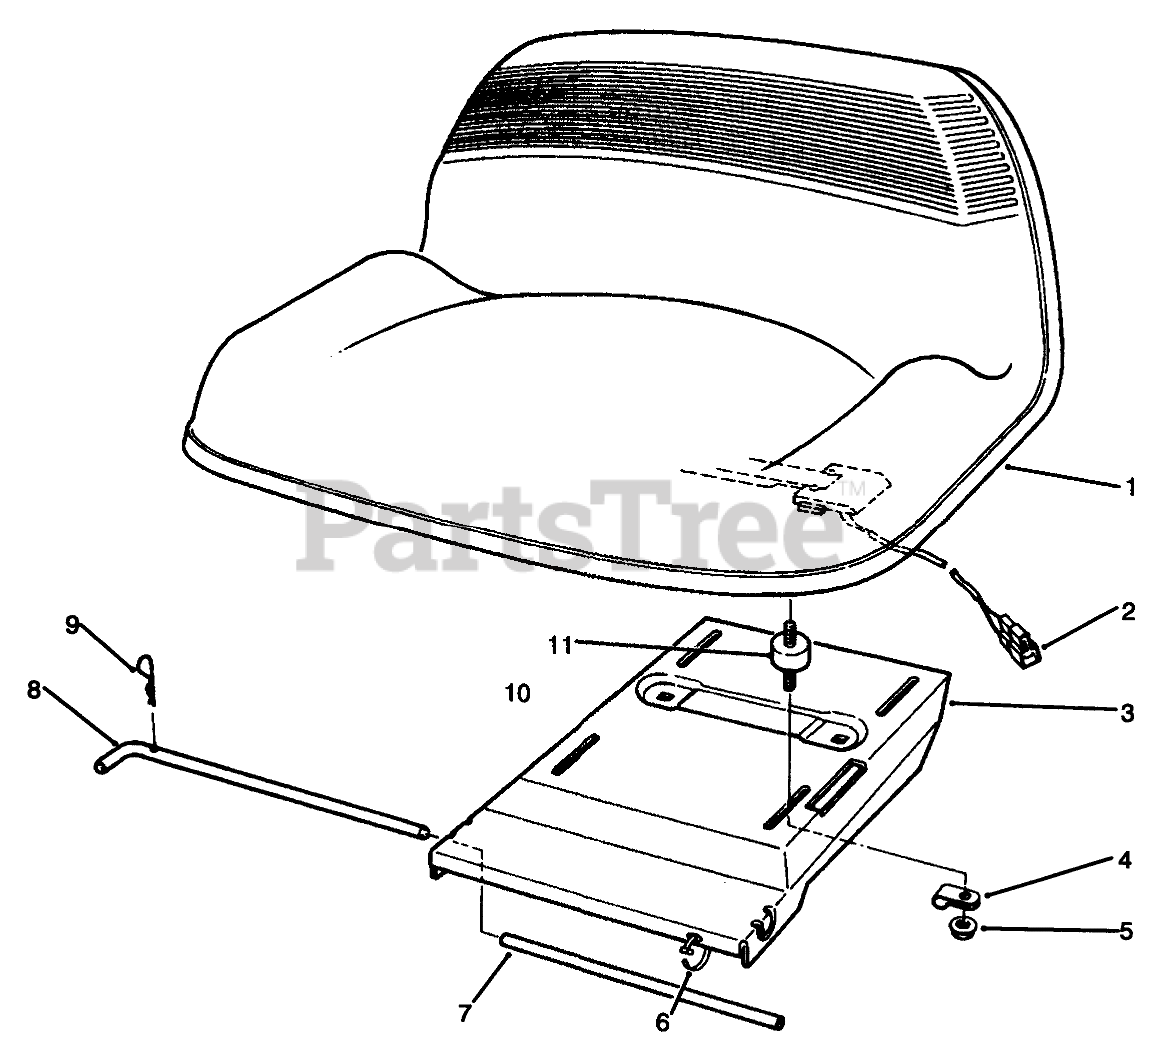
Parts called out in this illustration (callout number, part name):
1	SEAT
2	SWITCH-SEAT
3	Base-Seat
4	CLAMP
5	NUT-HF
6	TIE-CABLE
7	TUBE-SEAT
8	ROD-SEAT BASE
9	PIN-COTTER
11	ISOLATER-SEAT
